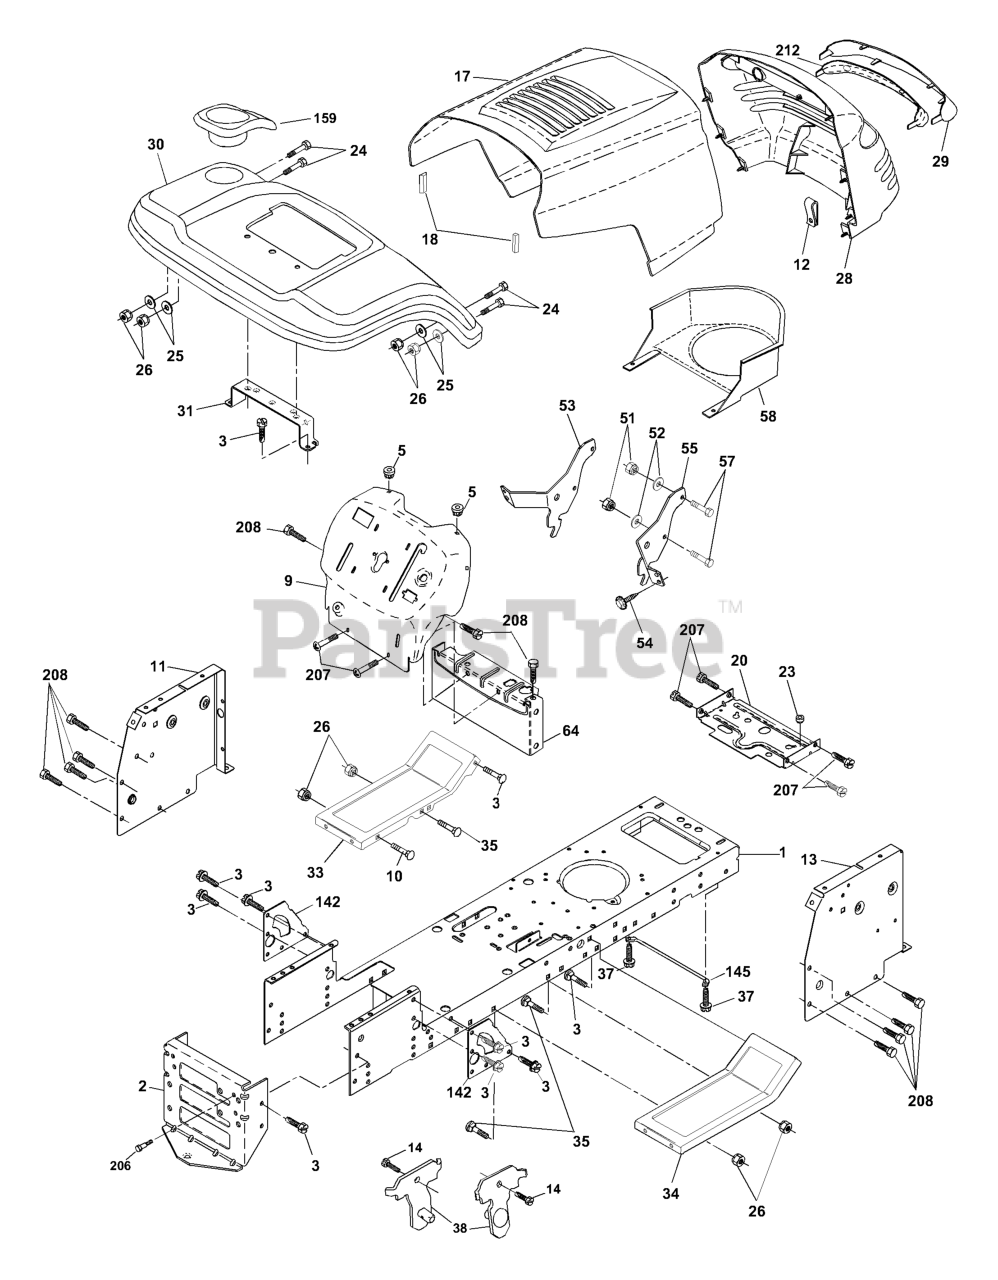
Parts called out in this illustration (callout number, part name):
1	CHASSIS STAMPING
2	DRAWBAR, 12GA
3	SCREW 3/8-16X3/4
5	BUMPER.RUBBER.HOOD
9	DASH SLKSCR
10	BOLT D
11	PANEL DASH LH
13	PANEL ASM, DASH RH
14	SCREW LT
17	HOOD ASM.
18	BUMPER HOOD T
20	PLATE MTG
23	BUSHING.SNAP.NYL.BLK.
24	BOLT
25	WASHER
26	NUT
28	GRILLE ASM
29	LENS
31	BRACKET FENDER
33	FOOT REST LH
34	FOOTREST RH
35	BOLT
37	Screw Thdrol 6/16-18 x 1/2 TYT
38	BRACKET
51	LOCKNUT.NYLOC.1/4-20
52	WASHER
53	BRACKET.GRILLE.LH
54	SCREW.HEX.WS.HD.8-18 X 7/8
57	BOLT
58	AIR DUCT P/L/LT
64	DASH LOWER
142	PLATE
145	ROD PIVOT CHASSIS/HOOD
159	CUPHOLDER
206	SHOULDER BOLT 5/16-18TT
207	SCREW, 5/16-18 X 1/2
208	SCREW 3/8-16X1/2
212	REPL BY 532 1745-03
